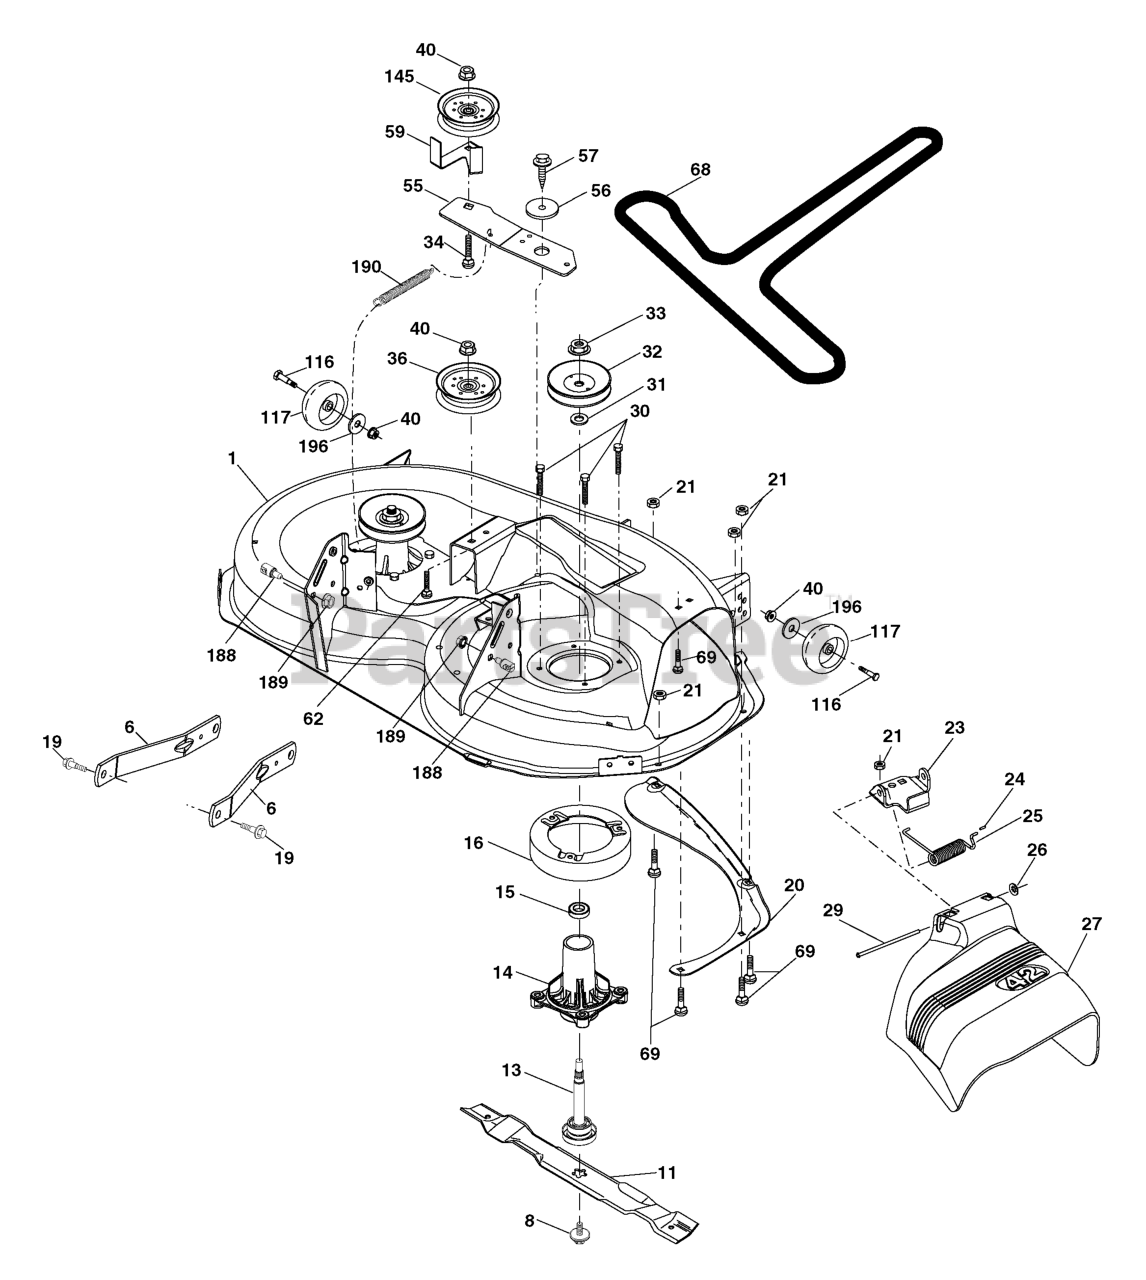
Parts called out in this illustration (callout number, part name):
1	DECK.WELDMENT.42"
6	ARM.SUSPENSION.MOWER.R
8	BOLT.WASHER.ASM.7/16-2
11	BLADE.42"MULCH.PREMIUM
11	42" HI-LIFT BLADE
11	BLADE.42".MULCH
13	SHAFT.ASM.MDRL.N/GREASE.38
14	RP.HOUSING.MANDREL.4PT.
16	STRIPPER.MANDREL.ROUND.BLACK
19	BOLT.SHOULDER
20	BAFFLE.VORTEX
21	LOCKNUT
23	BRKT.DEFLECTOR.38"2005+
24	CAP-SLEEVE LT
25	SPRING.TORSION.DEFLECT
26	NUT PUSH M
27	SHIELD.DEFLECTOR.MOWER.42"BLAC
29	ROD.HINGE
30	SCREW, WASHER HEAD
31	WASHER.SPACER.MANDREL
32	PULLEY MANDREL
33	NUT.FLANGE.LOCK.TOP
34	BOLT.3/8-16X1.50
36	PULLEY.IDLER.2006
40	NUT LOCK FLG 3/8-16 UNC
55	IDLER.ARM
56	SPACER.RETAINER
57	SCREW 3/8-16X1
59	GUARD, BELT
62	BOLT
68	BELT V SECONDARY
69	BOLT
116	BOLT.SHOULDER.3/8-16X3-5/8.
117	RP WHEEL. GUAGE RALLY
145	PULLEY.IDLER.FLAT
188	STUD.FASTNER.W/ANTI-ROTATE
189	NUT LOCK HEX FLANGE 5/16-18
190	SPRING.MOWER.DRIVE.ELECTRIC
198	WASHER
